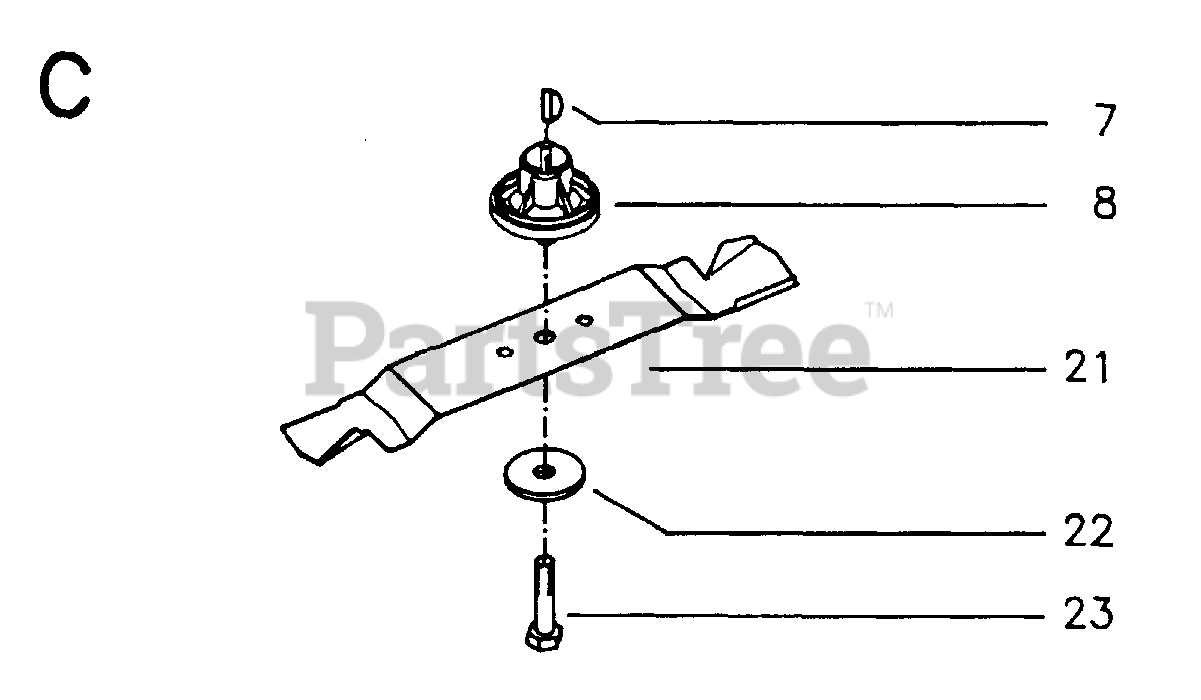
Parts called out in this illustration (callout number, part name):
7	WOODRUFF KEY
8	BLADE ADAPTER
21	BLADE
23	REPL BY 515 12 39-31
